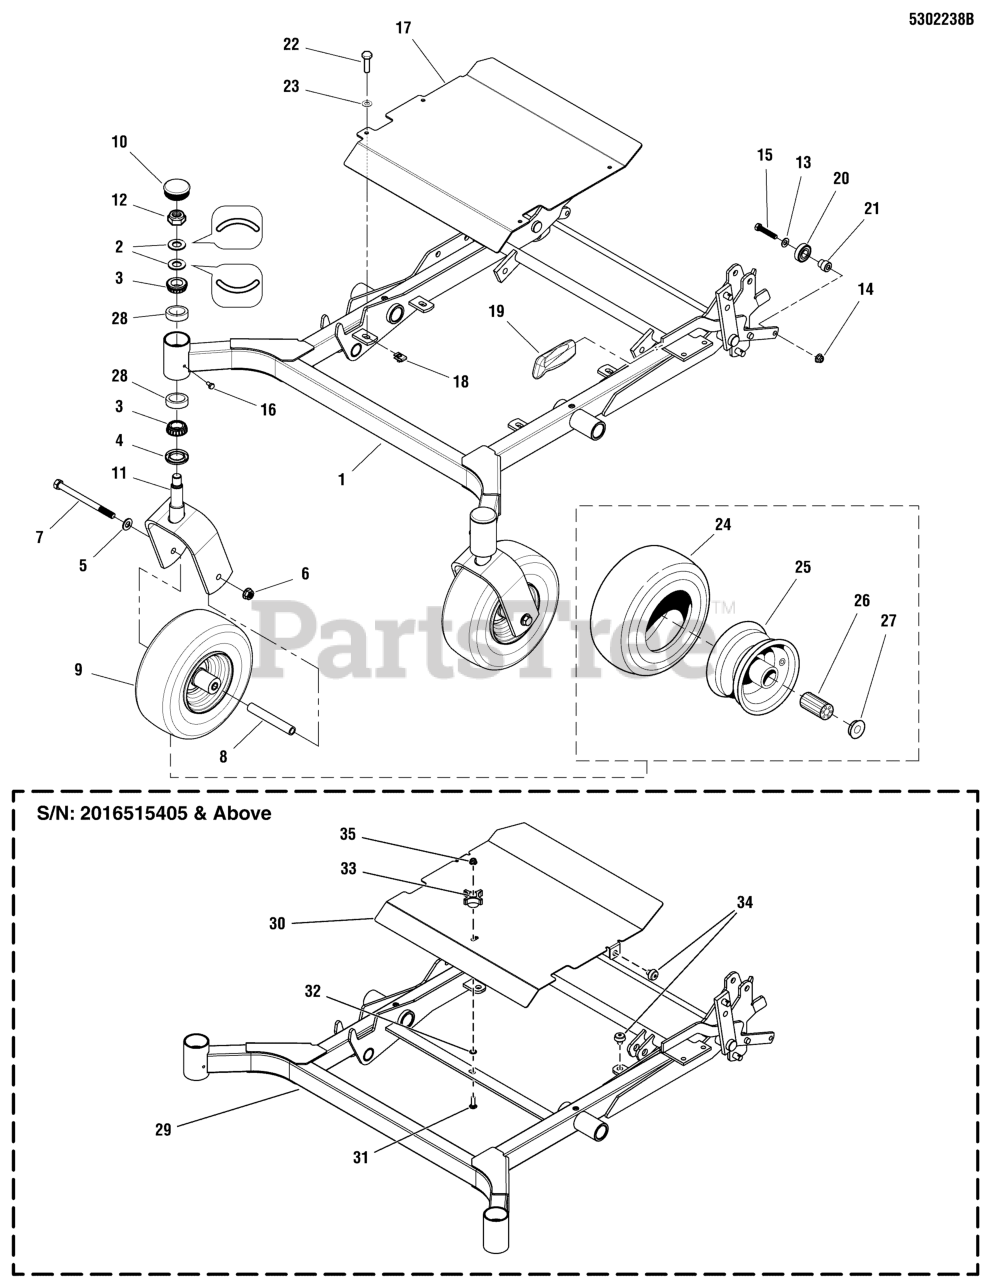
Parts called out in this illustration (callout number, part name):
1	WELD, MOWER FRAME - OUTFRONT - RED
2	WASHER, BELLEVILLE - 1.500 X .755
3	BEARING, TAPERED ROLLER, 1"
4	SEAL, GREASE
5	WASHER, 1/2 SAE
6	NUT, Hex Flange, Nylock, 1/2-13
7	BOLT, HEX, 1/2-13 X 7, GD 8, YZ
8	AXLE, Front Caster
9	WHEEL, CASTER, 11 X 4.0-5 SILVER BEAD LO
10	CAP, GREASE, LOW PROFILE
11	WELD., FRONT CASTER YOKES - RED
12	NUT, 3/4-16, HEX JAM NYLON LOCK
13	WASHER, 3/8 SAE
14	NUT, 3/8 - 16 HEX NYLOCK FLANGE
15	BOLT, 3/8-16 X 2, GD5, CZ
16	BOLT, 1/4-28 X 1/2, GD5 YZ
17	GUARD, BELT - CENTER - RED
18	BODY CLIP, 5/16-18 -1/4 MATERIAL
19	GRIP, BLACK FLEXIBLE
20	BEARING, BALL 11/16X1-9/16X15/32
21	SPACER, HYDRO PULLEY
22	BOLT, 5/16-18 X 1" GRD5 YZ
23	WASHER, 5/16" SAE
24	TIRE, FRONT, 11 X 4.0 - 5 (SV)
25	WHEEL FOR 11X4.0-5 TIRE ASSM
26	BEARING, CASTER WHEEL, 11 X 4.0 - 5 BEAD LOCK (SV)
27	RETAINER, BEARING (TWO PER TIRE)(SV)
28	CUP, BEARING (SV)
29	WELD, MOWER FRAME, 800 - 61" - RED
30	DECK GUARD, CENTER, 800 - RED
31	BOLT, 5/16-18 X 1, CARRIAGE, GD5, CZ
32	5/16" PUSH-ON NUT RETAINER, STL, CZ
33	KNOB-INT THR .312-18 4-ARM 2.12WD 1.06LG
34	MNT, VBRTN, RBBR
35	NUT, 5/16-18 HEX NYLOCK FLANGE NUT
